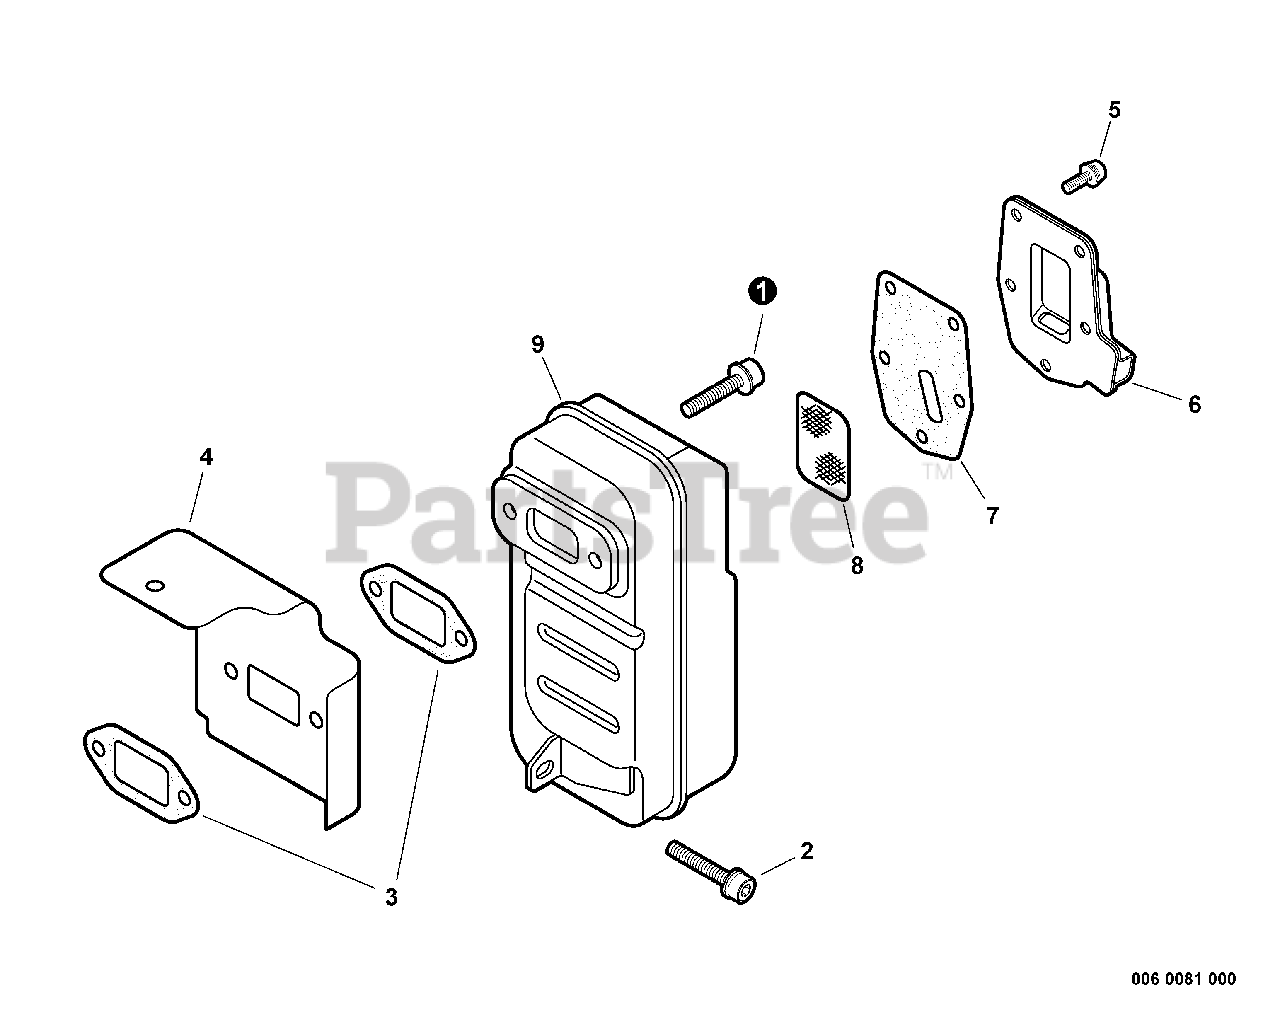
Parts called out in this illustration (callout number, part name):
1	BOLT 6×20
2	BOLT 5×20
3	GASKET, EXHAUST
4	COVER, ENGINE - EXHAUST
5	SCREW 4×10
6	GUIDE, EXHAUST
7	GASKET, EXHAUST
8	SCREEN, SPARK ARRESTER
9	MUFFLER
